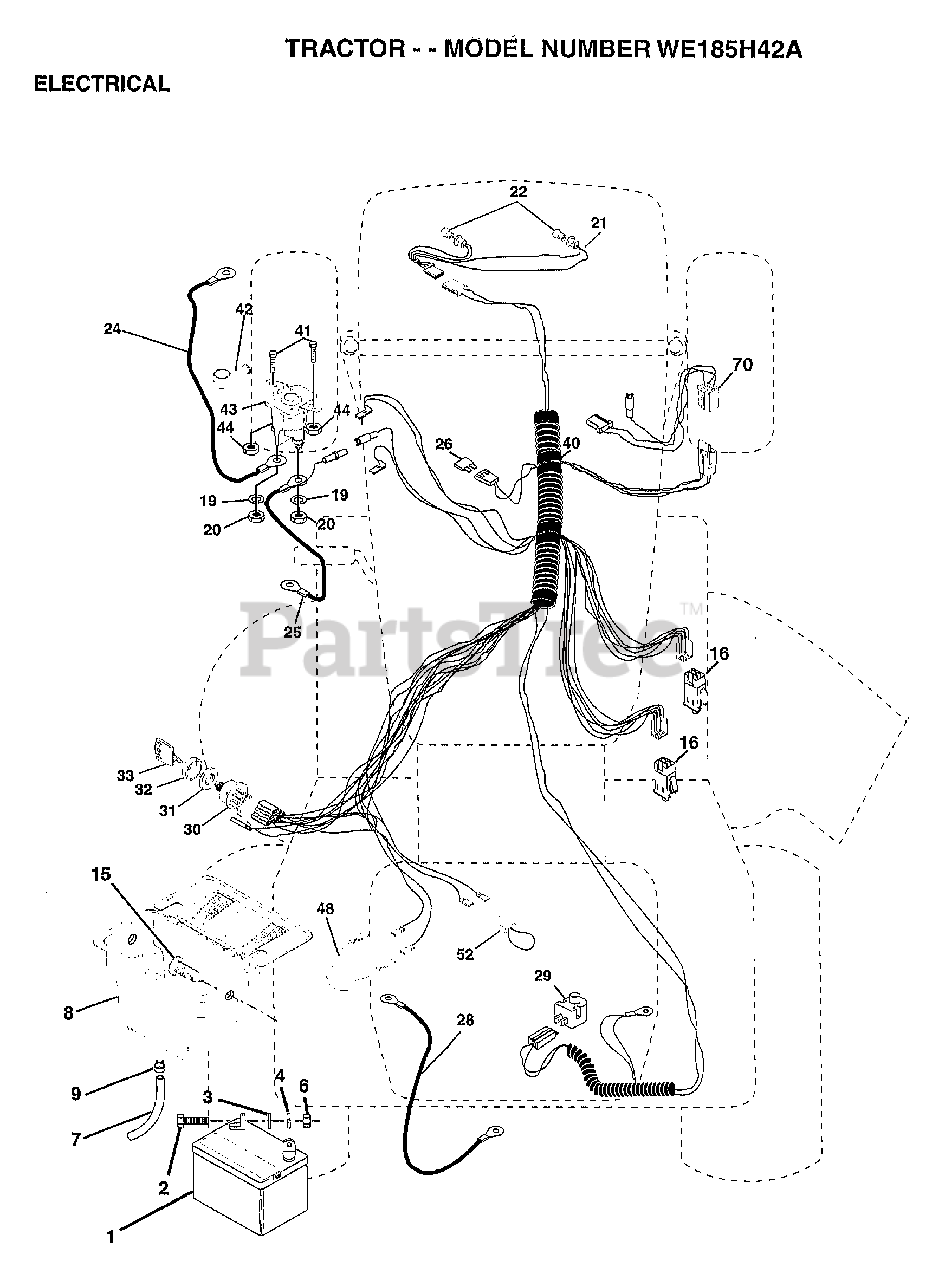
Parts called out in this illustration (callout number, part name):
2	BOLT LT
3	WASHER
4	LOCKWASHER
7	TUBE T
8	"CASE,BATTERY.MECH"
9	HOSE CLAMP T
15	FASTNER.SNAP-IN
16	SWITCH INTERLOCK
20	NUT
21	"HARNESS,LIGHT SOC"
22	HEADLAMP BULB
24	"CABLE T, BATTERY"
25	CABLE.BTRY.6GA.RD
26	FUSE HYT
28	CABLE T
29	SWITCH SEAT
30	SWITCH IGN 4POS
31	NUT IGNITION
32	COVER KEY SWITCH
33	KEY
40	HARNESS-IGNITION
41	BOLT HXHD FIN
44	NUT HXKEP 1/4X20
48	ADAPTER AMMETER
52	PROTECTION LOOP
70	HARNESS ENG DUAL
